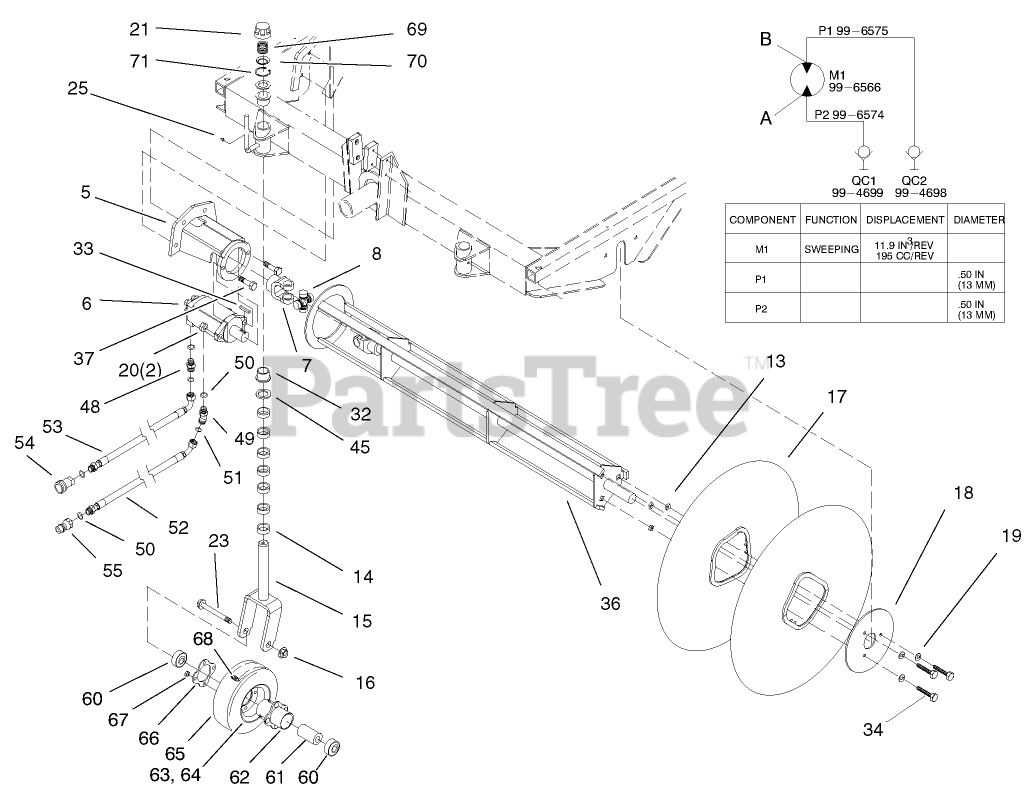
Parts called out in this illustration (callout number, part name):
5	HYD MOTOR MOUNT ASM
6	MOTOR-HYDRAULIC
7	YOKE-KEYED
8	CROSS-YOKE
13	RETAINER-NUT
14	SPACER
15	Caster Fork
16	NUT-LOCK, NI
17	ELEMENT-BRUSH, POLY
18	PLATE-RETAINER, BRUSH
19	WASHER-LOCK
20	NUT-HEX
21	HOC CAP ASM
23	SCREW-HH
25	FITTING-GREASE
32	Bushing
33	KEY-STEP
34	SCREW-HH
36	ROTOR FRAME ASM
37	SCREW-HH
45	WASHER
48	FITTING-STRAIGHT
49	FITTING-HYD-45
50	O-RING
51	O-RING
52	HOSE ASM
53	HOSE ASM
54	FEMALE-DISCONNECT, QUICK
55	MALE-DISCONNECT, QUICK
60	BEARING
61	SPACER-BEARING, INNER
63	RIM-WHEEL, HALF
64	RIM-WHEEL, HALF
66	PLATE
67	NUT-HHF
68	TUBE-INNER (W/VALVE)
69	SPRING-COMPRESSION
70	WASHER-CAP
71	RING-RETAINING
